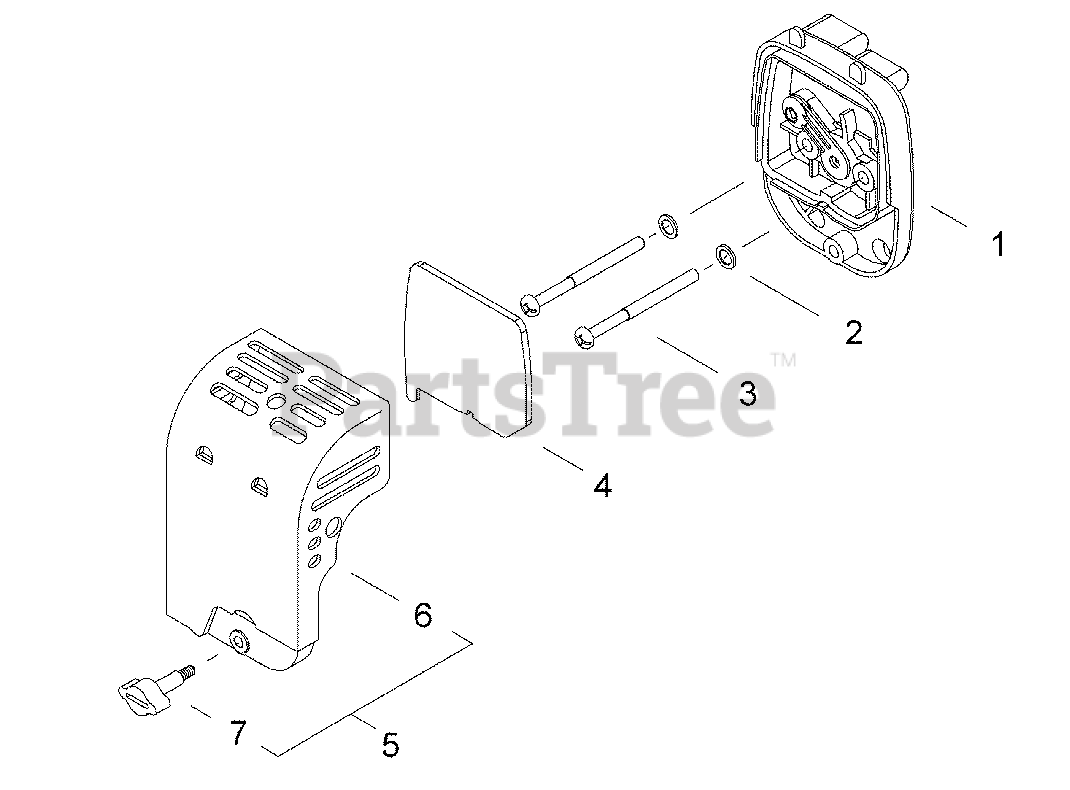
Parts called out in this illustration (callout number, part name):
1	CASE, AIR FILTER
2	WASHER - 5
3	SCREW - 5X60
4	FILTER, AIR
5	AIR FILTER COVER ASSY
6	COVER, AIR FILTER
7	THUMBSCREW
